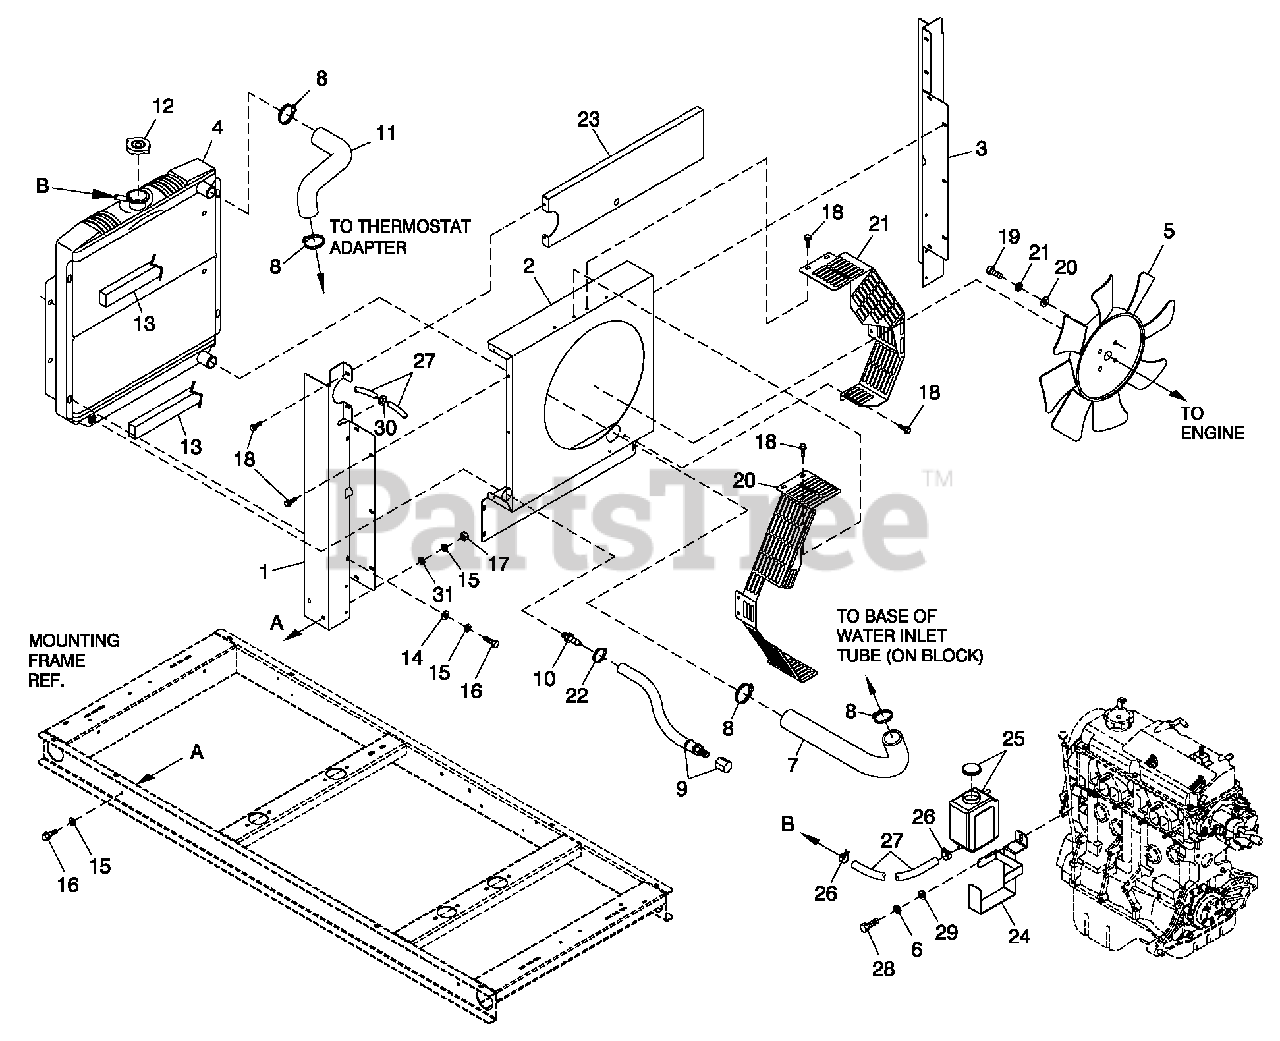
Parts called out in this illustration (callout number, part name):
1	SUPPORT RADIATOR LH SIDE
2	VENTURI 15" DIA FAN
3	SUPPORT RADIATOR RH SIDE
4	RADIATOR 2.5L CPL
5	FAN COOLING 15"
6	WASHER LOCK M8'5/16
7	RADIATOR HOSE LWR 1.5L C1 CPL
8	CLAMP HOSE #24 B1.06'2.00
9	HOSE OIL DRAIN ASSY 21"
10	BARBED STR 1/4 NPT X 3/8
11	HOSE ' UPPER RADIATOR
12	CAP RADIATOR
13	TAPE FOAM 1 X 1 (17" LG)
14	WASHER FLAT 1/4'M6 ZINC
15	WASHER LOCK M6'1/4
16	SCREW HHFC M6'1.0 X 20 G8.8
17	NUT HEX M6 X 1.0 G8 YEL CHR
18	SCREW THF M6'1 X 16 N WA Z/JS
19	SCREW HHC M6'1.0 X 70 G8.8
20	GUARD FAN LH C1 CPL
21	GUARD FAN RH C1 CPL
22	CLAMP HOSE .38'.87
23	BLOCK OFF UPPER
24	BRACKET 2.5L FORD WATER BOTTLE
25	TANK COOLANT RECOVERY
26	CLAMP HOSE BAND 1/4
27	HOSE 9/32 ID (40" LG)
28	SCREW SHC M8'1.25 X 20 G12.9
29	WASHER FLAT 5/16'M8 ZINC
30	GROMMET 7/8 X 3/16 X 5/8
31	WASHER SHAKEPROOF EXT 1/4 STL
